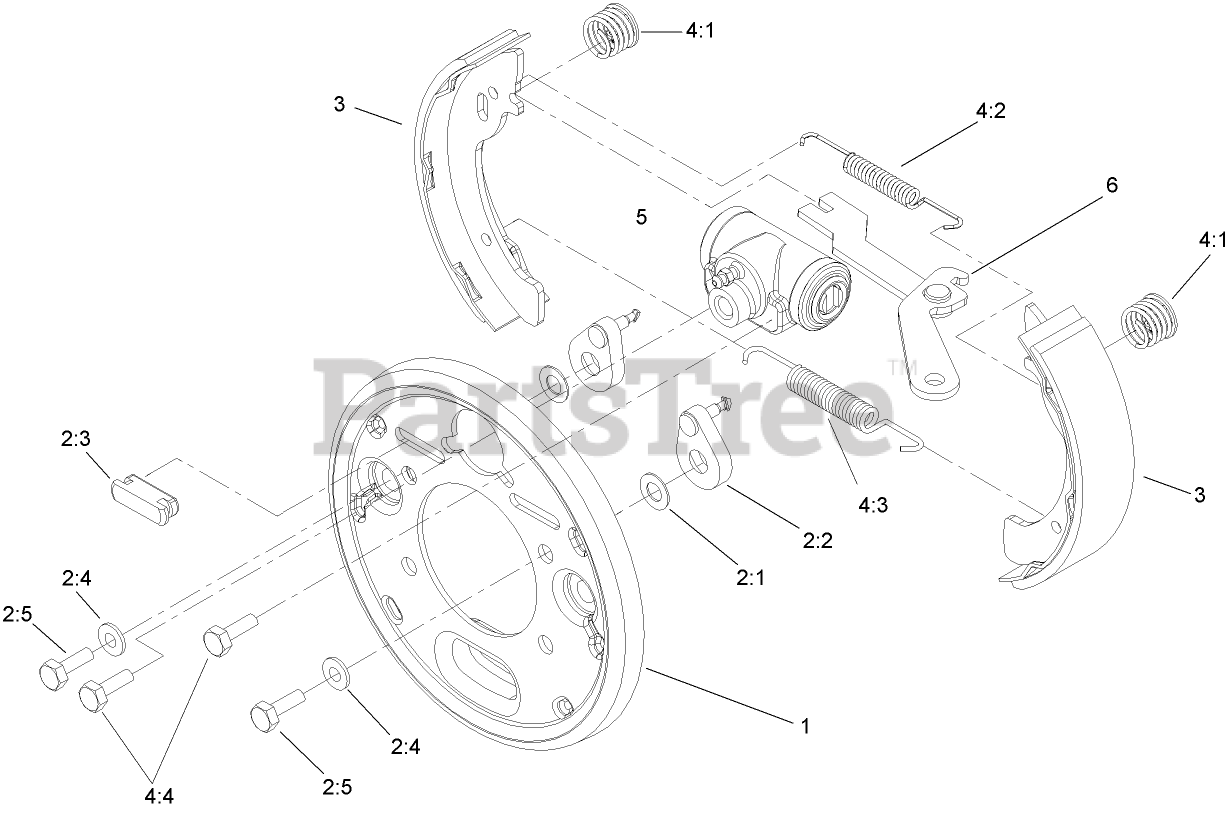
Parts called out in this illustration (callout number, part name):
1	BACKING PLATE ASM
2	ADJUSTER KIT
2:1	WASHER-BELLVILLE
2:2	ADJUSTER LEVER ASM
2:3	COVER-DUST
2:4	Washer
2:5	Bolt
3	SHOE AND LINING KIT
4	HARDWARE KIT
4:1	SHOE HOLD DOWN SPRING ASM
4:2	SPRING-UPPER
4:3	SPRING-LOWER
4:4	Loose Parts Package
5	WHEEL CYLINDER ASM
6	RH PARK BRAKE LEVER ASM
